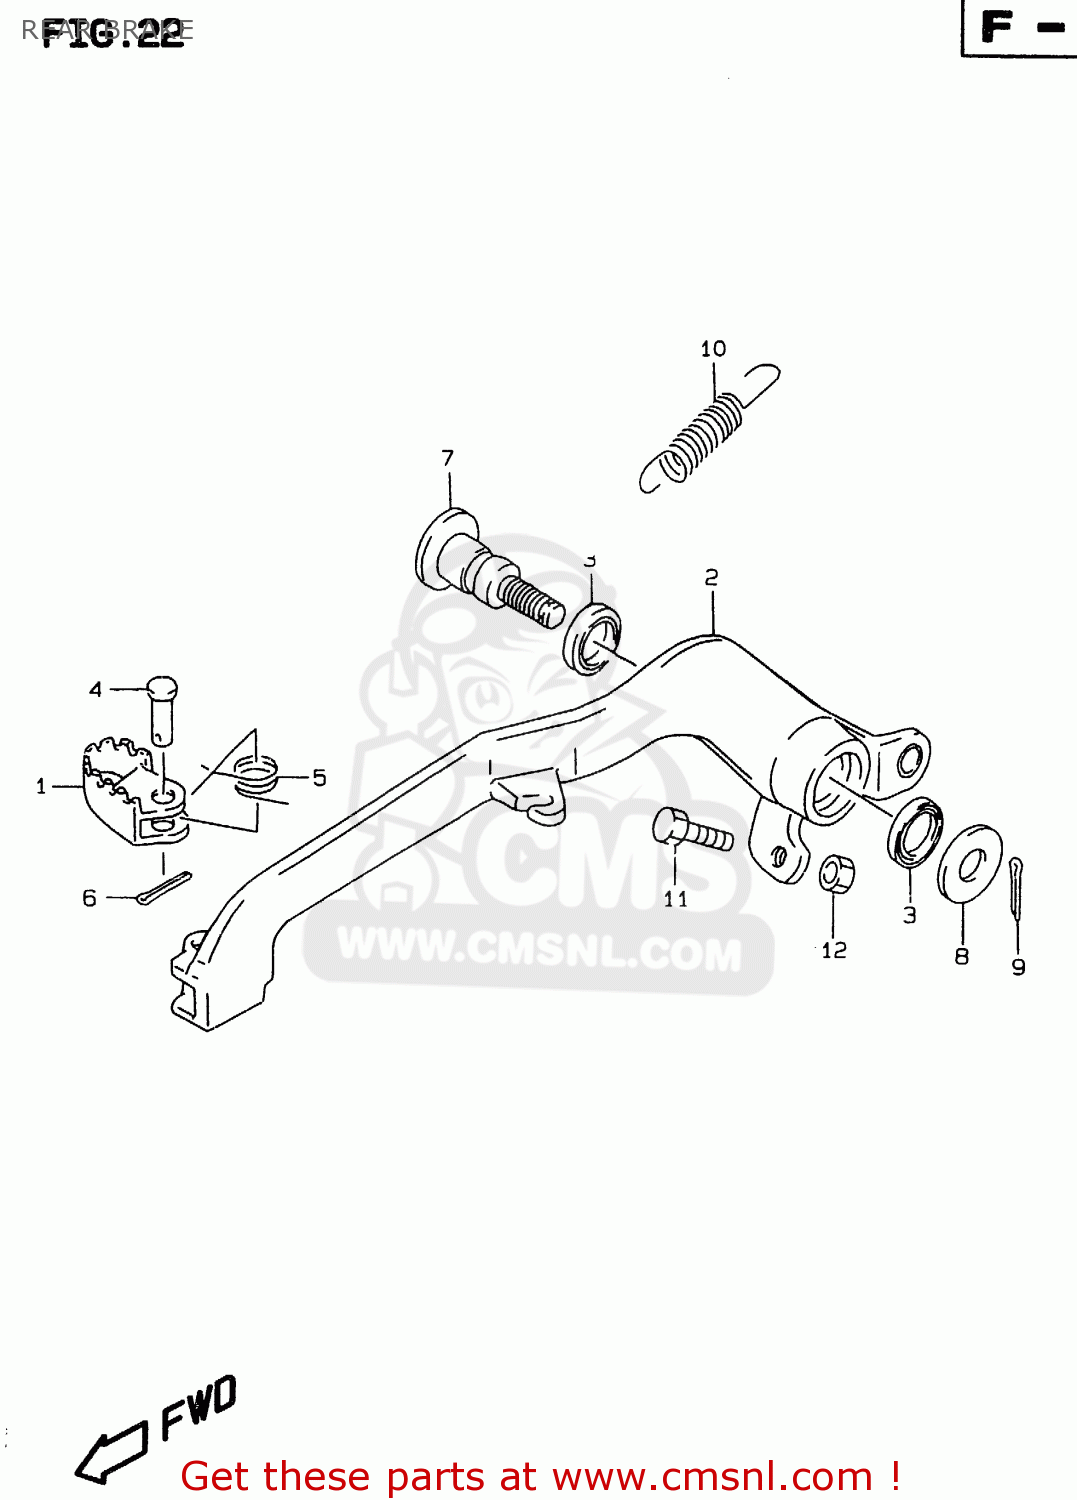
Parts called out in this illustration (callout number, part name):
1	PEDAL,BRAKE
2	ARM,BRAKE PEDAL
3	SEAL,OIL(15X21X3)
4	PIN(6X23.5)
5	SPRING
6	PIN
7	SHAFT,BRAKE PEDAL
8	WASHER
9	PIN 20X20
10	SPRING
11	BOLT(6X23)
12	NUT 6MM
